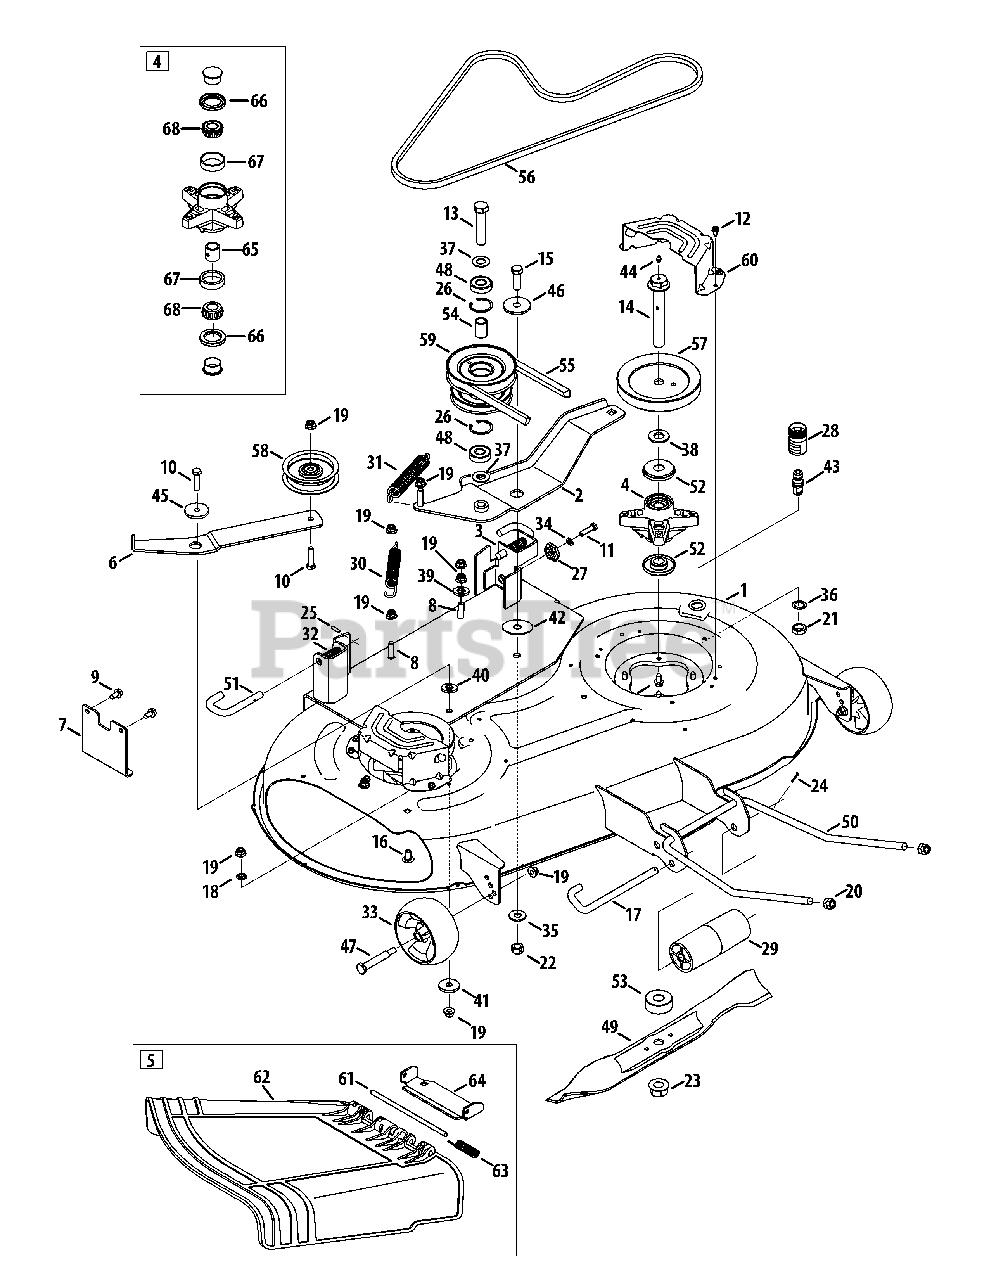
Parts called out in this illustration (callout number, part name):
1	Deck Assembly
2	PTO Idler Assembly
3	Hanger Adjustment Bracket
4	Spindle Assembly
5	Chute Assembly
6	Idler Bracket
7	Up-Stop Front Bracket
8	Carriage Bolt, 3/8 x 16 x 1.50
9	Hex Washer Screw, 5/16-18 x .750
10	Hex Screw, 3/8-16 x 1.50
11	Hex Screw, 5/16-18 x 1.25
12	Hex Washer Screw, 1/4-20 x .500
13	Hex Screw, 5/8-18 x 3.00
14	Spindle Bolt, 3/4-16 x 5.37
15	Hex Screw, 1/2-20 x 1.50
16	Carriage Bolt, 3/8-16 x .75
17	Roller Pin, 1/2 x 7.31
18	Push Nut, 3/8
19	Flange Lock Nut, 3/8-16
20	Flex Lock Nut, 1/2-13
21	Hex Nut, 16-1.5
22	Hex Lock Nut, 1/2-20
23	Flange Lock Nut, 3/4-16
24	Cotter Pin, 3/32 x 1.25
25	Spirol Spring Pin
26	Retainer Ring
27	Deck Adjustment Gear
28	Water Nozzle Adapter
29	Front Roller
30	Extension Spring, .850 x 6.415
31	Extension Spring, 1.0 x 6.140
32	Compression Spring, .66 x 1.8
33	Deck Wheel, 5.0
34	Lock Washer, 5/16
35	Flat Washer, .531 x 1.25 x .100
36	Lock Washer, 5/8
37	Flat Washer, .65 x 1.25 x .075
38	Flat Washer, .760 x 1.50 x .120
39	Flat Washer, .510 x 1.000 x .125
40	Flat Washer, .385 x 1.0 x .030
41	Flat Washer, .45 x 1.5 x .172
42	Flat Washer, .535 x 1.92 x .060
43	Deck Water Nozzle
44	Drive Lube Fitting, 3/16
45	Shoulder Spacer, .8840 x .190
46	Shoulder Spacer, .9790 x .2025
47	Shoulder Screw, 1/2 x 2.50
48	Ball Bearing, .625 x 40 x 12
49	3-in-1 Blade, 21" (stamped 742-04101)
49	2-in-1 Blade, 21" (stamped 742-04374)
50	Front Lift Rod
51	Mower Support Pin
52	Deck Spindle Spacer
53	Spacer, .760 x 2.000 x .790
54	Spacer, .88 x .635 x 1.25
58	Idler Pulley
59	Double Pulley
60	Belt Cover
62	Chute Deflector
63	Torsion Spring, .44 x 2.0
64	Chute Bracket
65	Bearing Spacer, .78 x 1.0 x 1.0425
67	Bearing Cup, .750
68	Cone Bearing, .750
